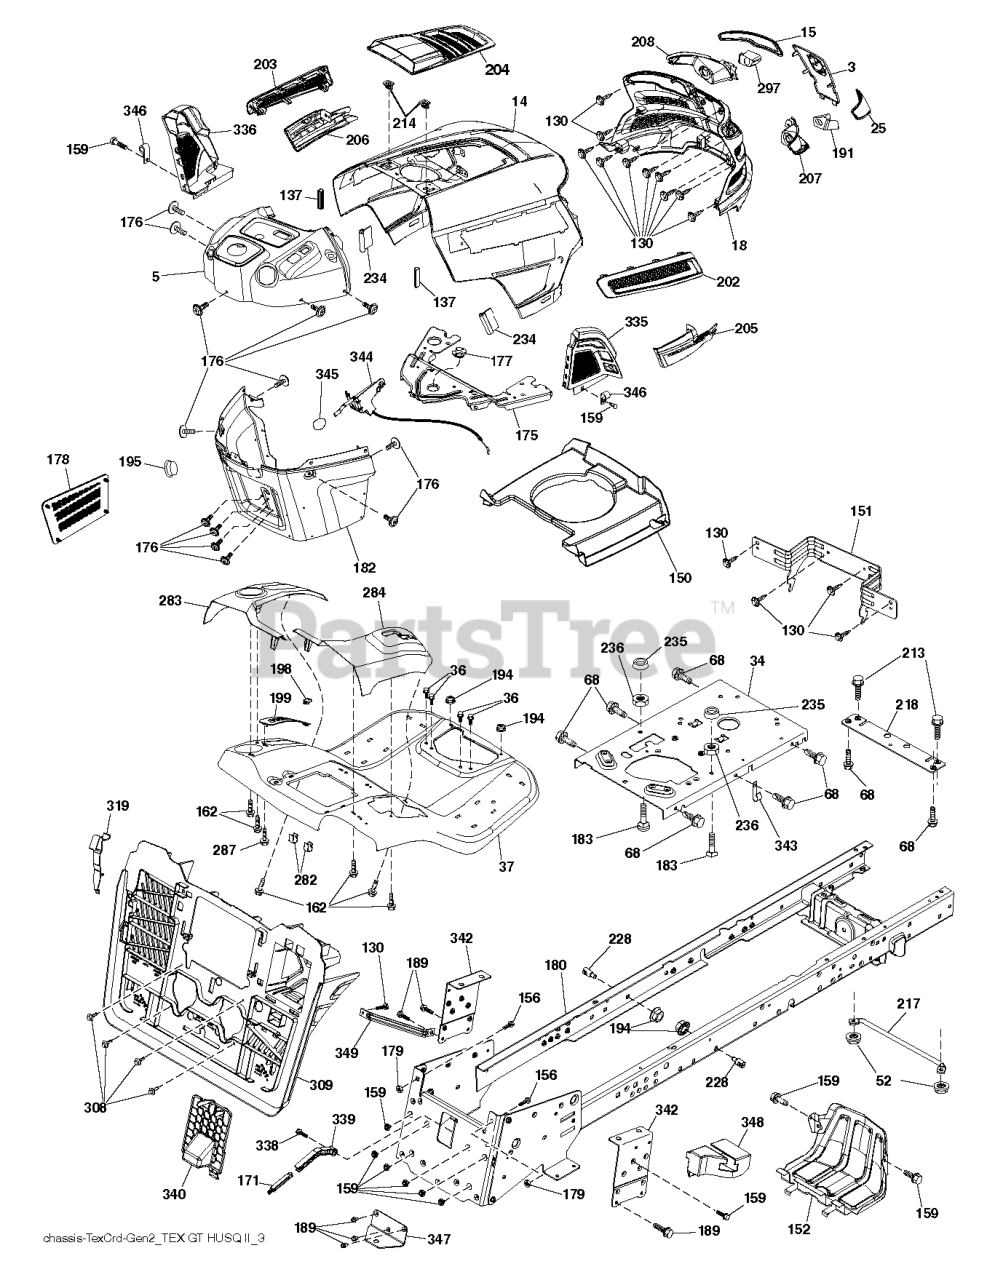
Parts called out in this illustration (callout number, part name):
3	APPLIQUE.SUBASM.GT.HUSQ.II
5	DASH.UPP.GT2.SM.PTO.MC.HR.GREY
14	HOOD.ASM.HUSQVARNA.GT.TEX.ORAN
15	LENS.HEADLIGHT.LH.GTII.2011
18	GRILLE.SUBASM.GT.HUSQ.II
25	LENS.HEADLIGHT.RH.GTII.2011
34	PLATE.ENGINE.WELDED.CHASSIS
36	SCREW 5/16"
37	FENDER.TEX.SRD.CRD.FRN.GUARDS
52	LOCKNUT
68	SCREW LT
130	SCREW.#10 X 0.750.BOS
137	BUMPER DASH
150	AIR DUCT.GTV2(1.66"RING HEIGHT
151	BRACKET.PIVOT.HOOD.GT.HUSQ.II
152	SHIELD.BROWNING.PNT.GT.V2
156	BOLT
159	SCREW, 3/8-16X3/4
162	SCREW.HI-LO.CONSOLE
171	EXTENSION.BAGGER.FULL.
175	PLATE.CROSSMEMBER.HUSQ
176	SCREW.#10-24X5/8.RN.QU
177	BUSHING, STEERING
178	CARGO.ASM.NET.TXGT.W/C
182	DASH DASH LOWER
183	BOLT.5/16-18X1-1/4 FULL THD
189	SCREW
191	INSERT.REFLECTIVE.RH.HUSQ.GTII
194	NUT LOCK HEX FLANGE 5/16-18
195	PLUG.HOLE.DASH.LOWER.12V.BLK
198	INDICATOR.DECK.LIFT.RED
199	PLATE DECK LIFT
202	VENT.SIDE.RH.GT.HUSQ.II.
203	VENT.SIDE.LH.GT.HUSQ.II.498
205	SIDE.TRIM.RH.GT.HUSQ.II
206	SIDE.TRIM.LH.GT.HUSQ.II.GRAY
207	BEZEL LIGHT.RH.GT.II.MYLAR
208	BEZEL LIGHT.LH.GT.II.MYLAR
213	BOLT
214	CLIP.RETAINER.TINNER.
217	ROD.PIVOT.HOOD
218	X-PIECE.HOOD.STOP.NON/
228	STUD.FASTNER.W/ANTI-ROTATE
234	BUMPER.HOOD.TEX.HUSQVARNA
235	SPACER FENDER
236	NUT.CENTERLOCK.5/16-
282	CLIP.RETAINER.CONSOLE.LT.HUSQ
283	CONSOLE.DECKLIFT.CRDII.498
284	CONSOLE.PEDAL.HYDRO
287	SCREW 1/4X20
297	INSERT.REFLECTIVE.LH.HUSQ.GTII
308	BOLT.5/16-18UNCX3/4 W/SEMS.BLK
335	COVER.RH.CLOSE.OUT.BLACK
336	COVER-LH.LOWER.DASH.GT2.BLACK
338	BOLT BOLT SHOULDER
339	LEVER.BAGGER.FULL.TEX.
342	SUPPORT SUPPORT FENDER
343	CLIP CLIP
344	CONTROL.EZ.MULCH.TEX/CRD
345	RP KNOB.OVAL.TAPERED.3/8-16BLK
346	CLIP,INSULATOR
347	HITCH TOW
349	BRACKET.SUPPORT.LRVB/CRD
